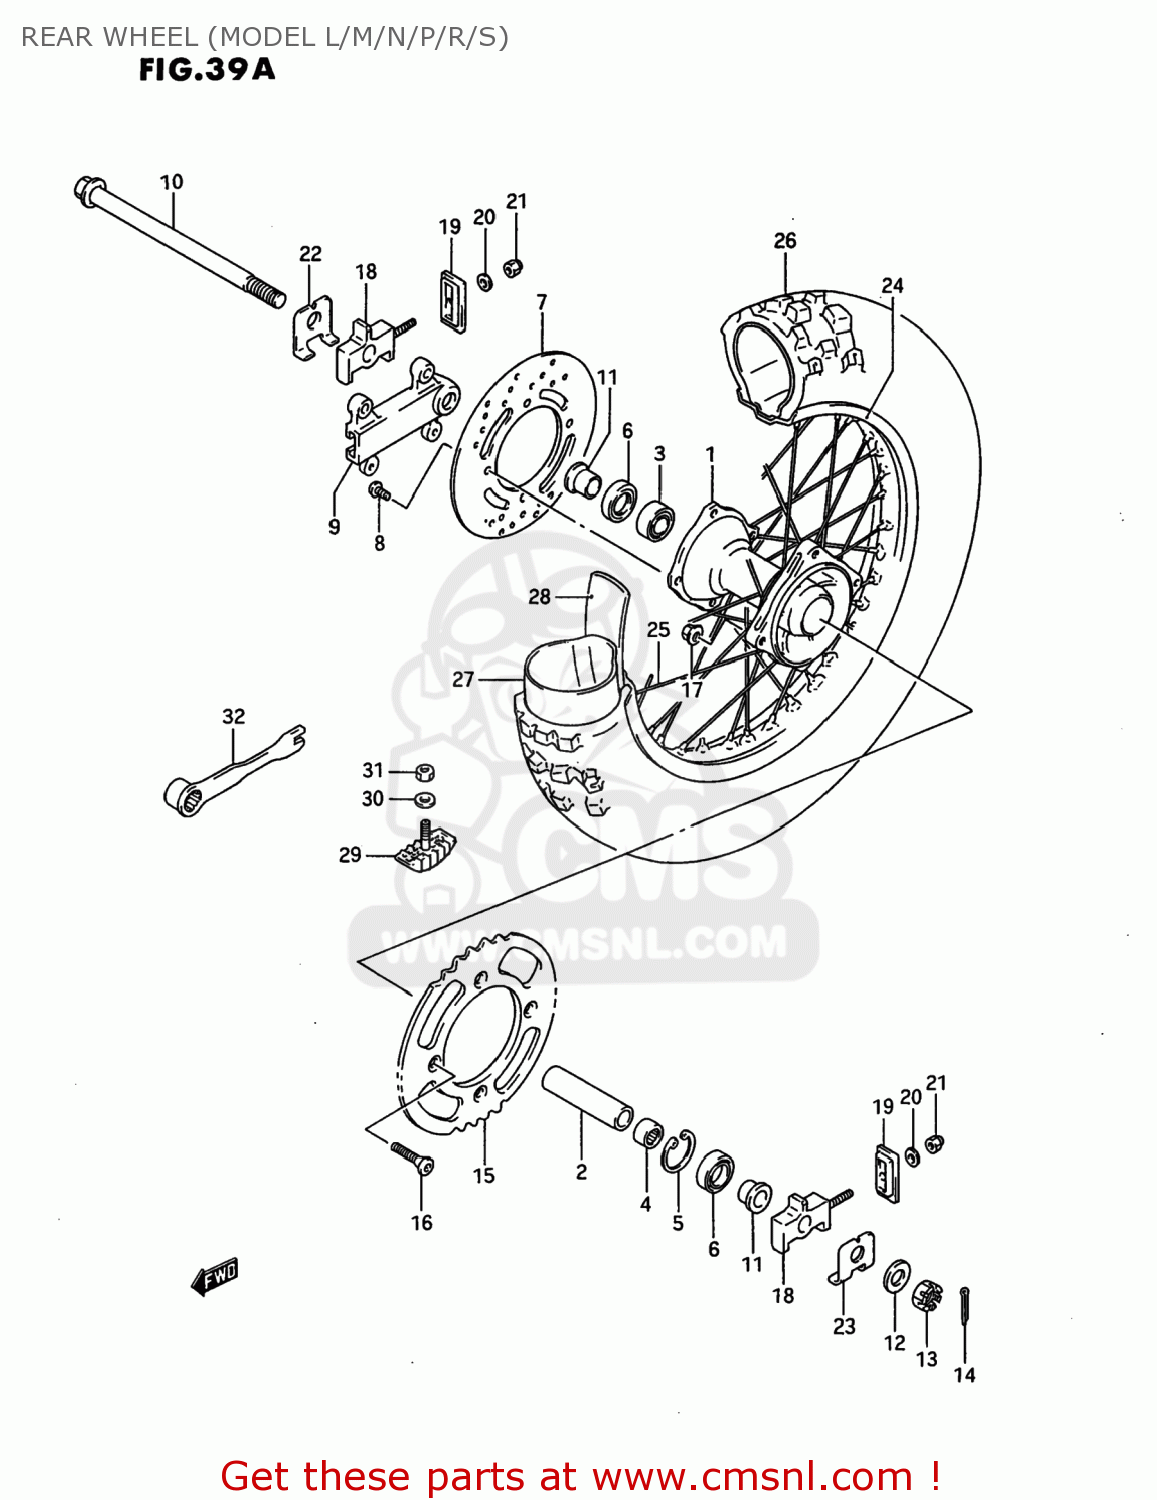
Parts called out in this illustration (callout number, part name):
1	HUB,REAR WHEEL
2	SPACER,RR HUB BEARING
3	BEARING
4	BEARING(15X35X11)
5	CIRCLIP
6	SEAL,OIL(20X35X7)
7	DISC,REAR BRAKE
8	SCREW
9	BRACKET,REAR CALIPER
10	AXLE,RR
11	SPACER,REAR AXLE
12	WASHER
13	NUT
14	COTTER PIN
15	SPROCKET,RR(49T)
16	BOLT(8X30.5)
17	NUT
18	ADJUSTER,CHAIN
19	PLATE,CHAIN ADJUSTER
20	WASHER
21	NUT 6MM
22	WASHER,CHAIN ADJUSTER RH
23	WASHER,CHAIN ADJUSTER,L
24	RIM,RR WHEEL(1.60X14 AL)
25	SPOKE SET,RR WHEEL
26	TIRE,RR(90/100 14)
27	TUBE ASSY,WHEEL INNER
28	PROTECTOR,WHL INR TUBE
29	STOPPER,BEAD
30	WASHER
31	NUT
32	SPARK PLUG WRENCH 21 & SPANNER 5.1
